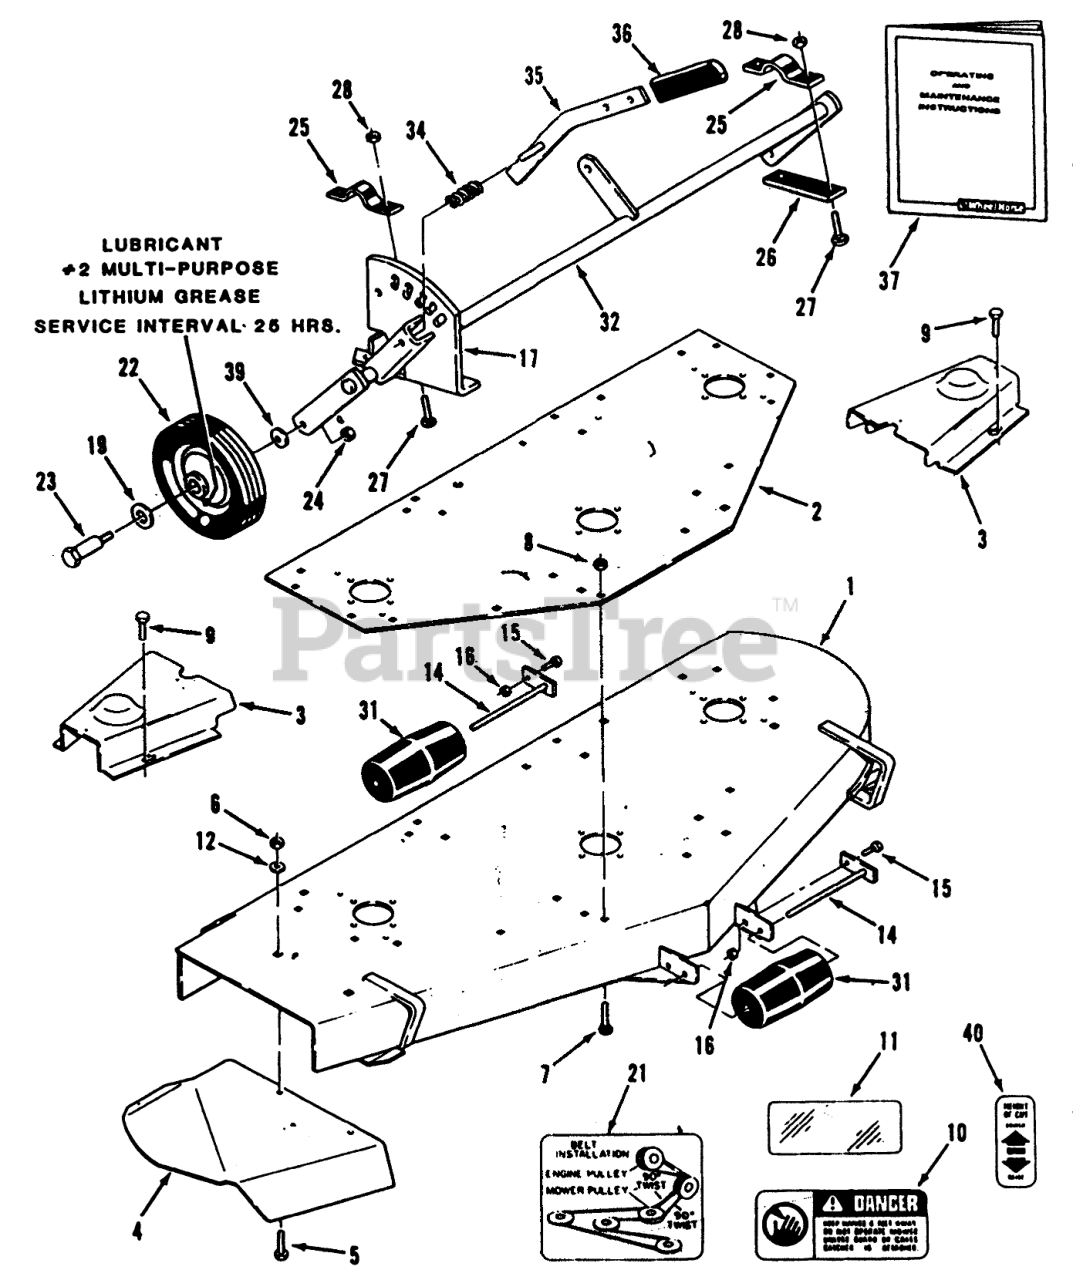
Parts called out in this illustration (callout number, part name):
1	ASS'Y-MOWER DECK R
2	PLATE-TOP REINFOR R
3	Belt Cover
4	CHUTE-DISCHARGE 6 R
5	Bolt
6	NUT
7	Bolt
8	NUT
9	Bolt
10	Danger Decal
11	DECAL-OVERLAY
12	Washer
14	ROLLER-SHAFT
15	Bolt
16	Nut
17	QUADRANT R
19	Washer
21	DECAL-BELT INSTALL
22	ASSY-GAUGE WHEEL
23	Bolt 3/8-16 x 3 1/4
24	NUT
25	Clamp
27	Bolt
28	NUT
31	ROLLER-ANTI SCALP
32	Gage Wheel Support
34	SPRING-COMPRESSION
35	Lever
37	Owner-s and Maintenance Instructions
39	SPACER
40	DECAL-HOC
55	Pulley Box Assembly
